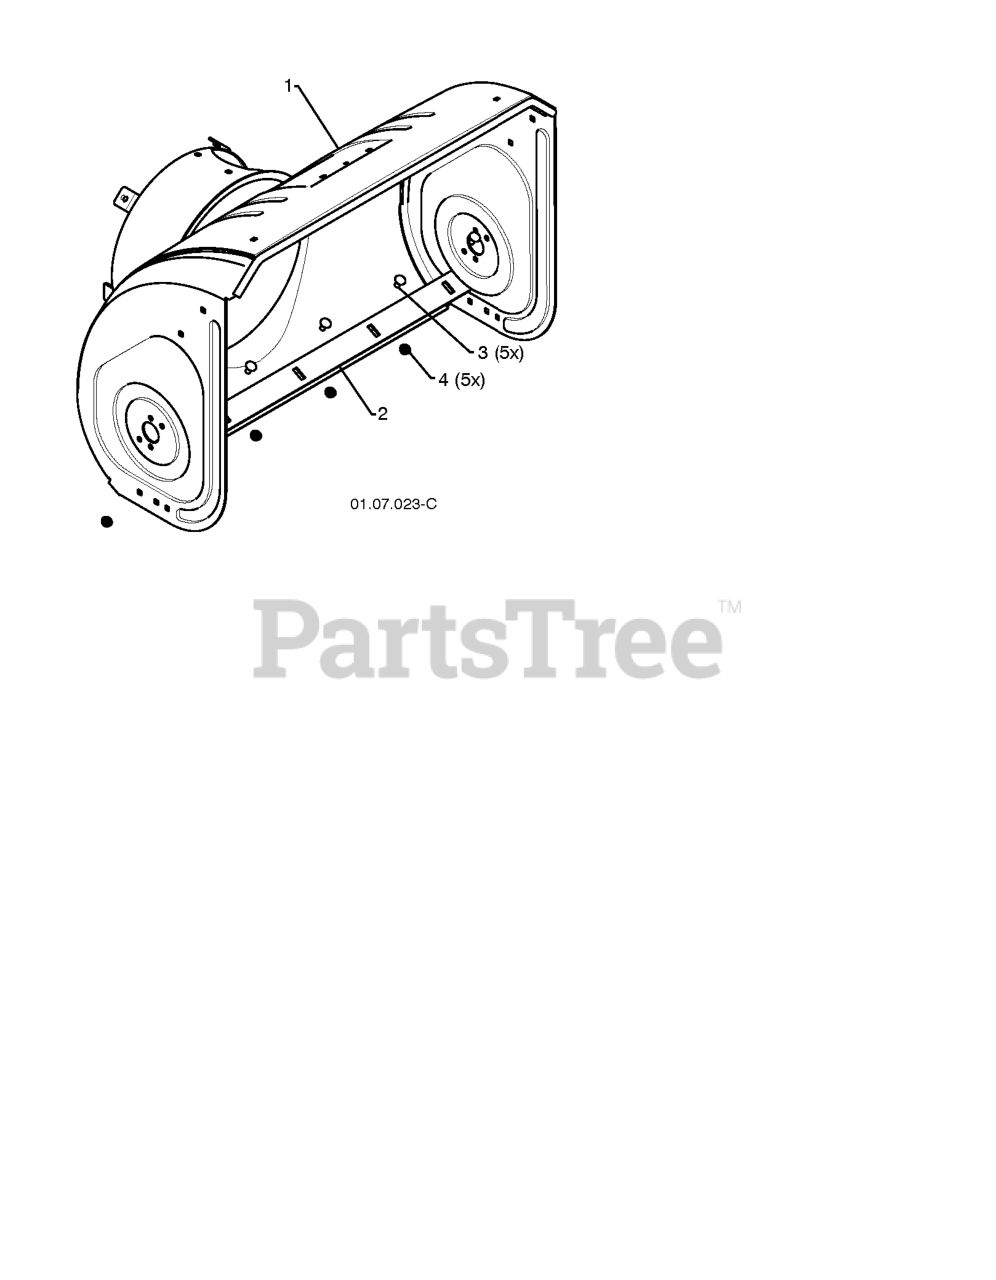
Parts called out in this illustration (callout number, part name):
1	HOUSING.AUG.WELDMENT.30.ORANGE
2	BAR, SCRAPER
3	BOLT
4	NUT.FLANGE.5/16
